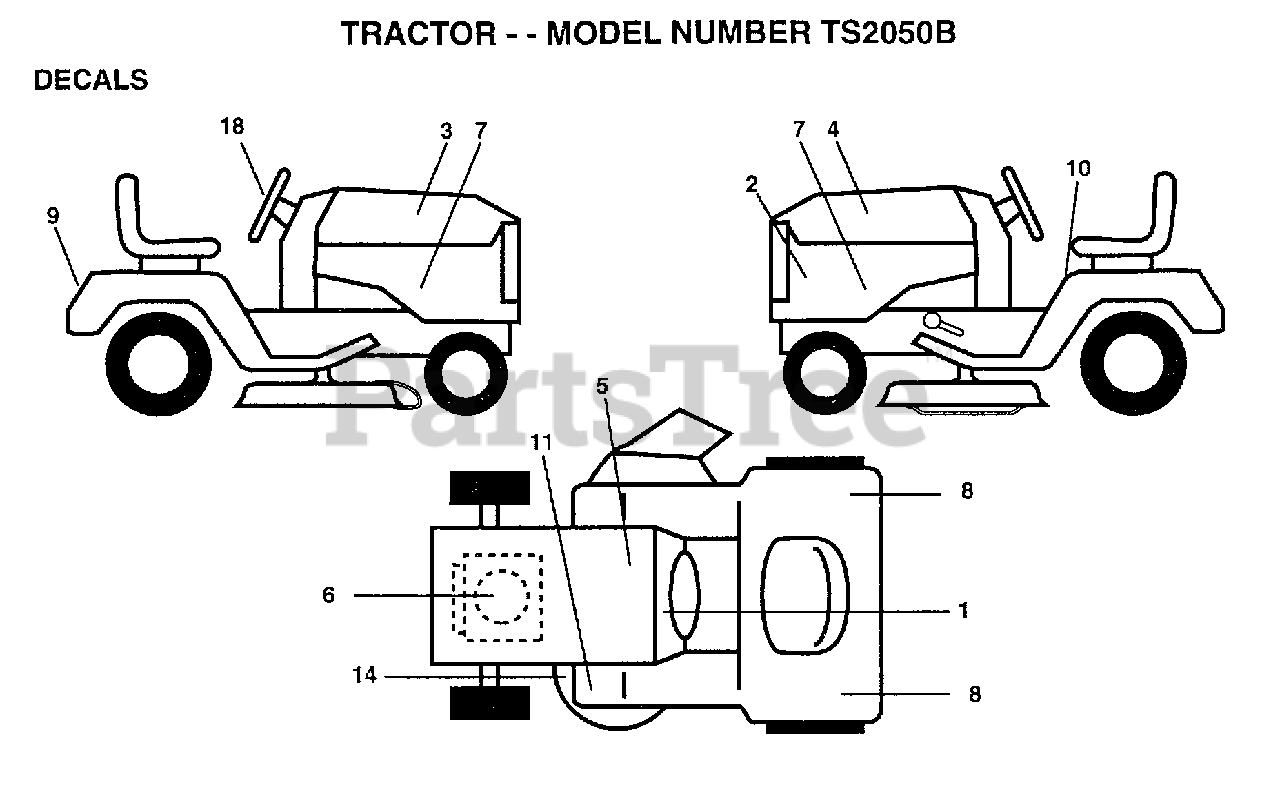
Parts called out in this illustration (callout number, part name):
1	DECAL.DASH.INST.
2	NAMEPLATE.HUSK.LG
3	DECAL.HD.RH.20/50
4	DECAL.HD.LH.20/50
5	DECAL.BTRY.DANGER
6	DECAL ENGINE
7	DECAL.PNL.SD.20HP
8	REFLECTOR-TAIL YT
9	DECAL.FEND.YT/GT
10	DECAL
14	"DECAL.V.BELT.44"""
18	DECAL.INS.STG.WHL
